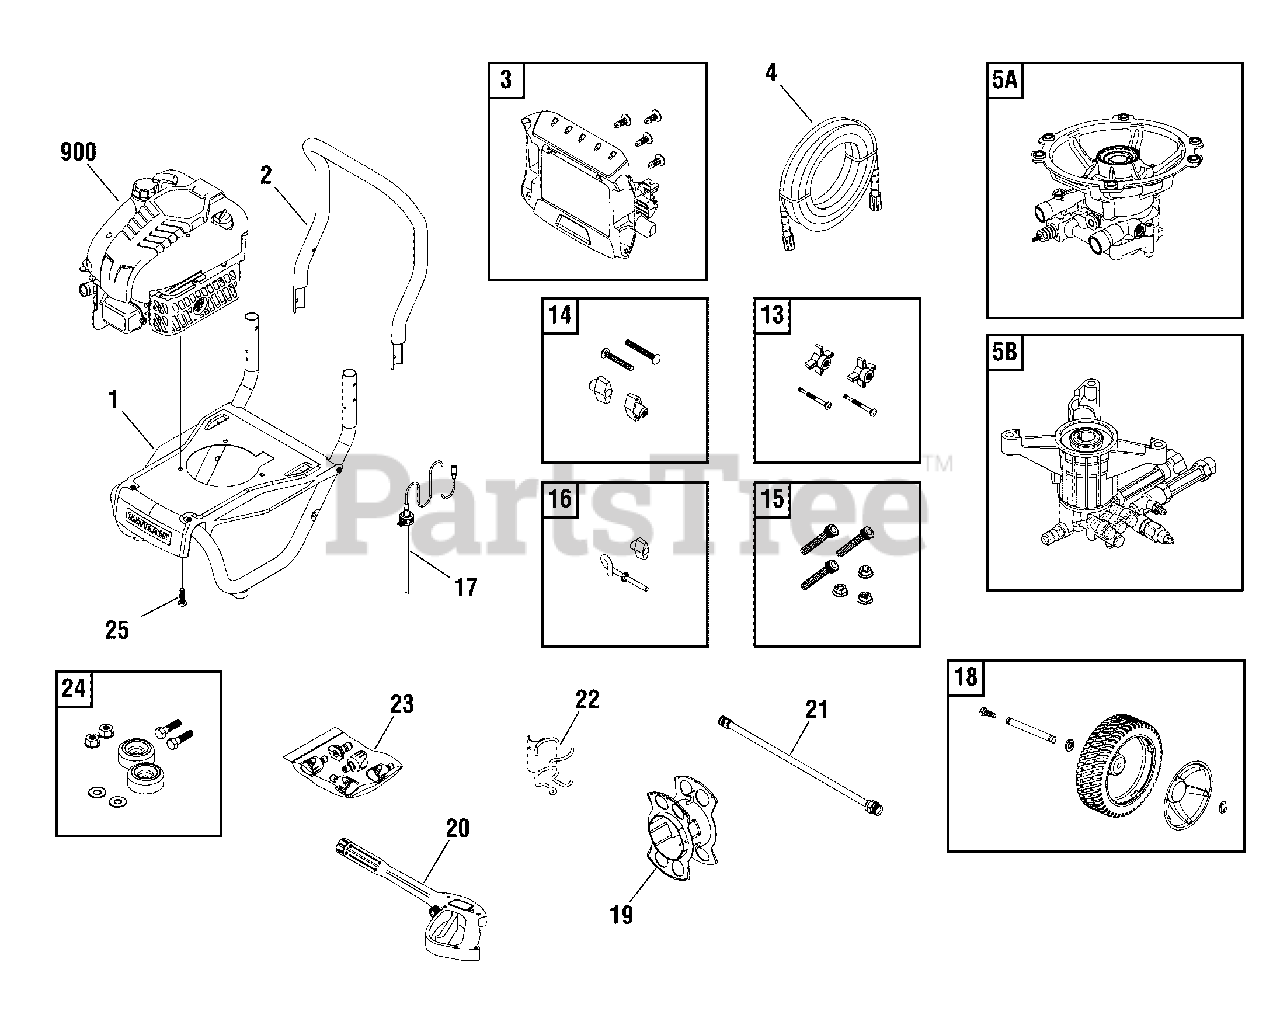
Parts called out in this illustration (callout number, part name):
1	Base, w/Vib Mounts
2	Handle
3	Kit, Billboard w/Clips & Decals
4	Hose
5A	PUMP
15	Kit, Pump Mounting Hardware
16	Kit, Rope Guide
20	Gun
21	Extension, QC
22	Wireform
24	Kit, Vibration Mount
25	HHS, Trilobular, 3/8-16 x 1-1/4
